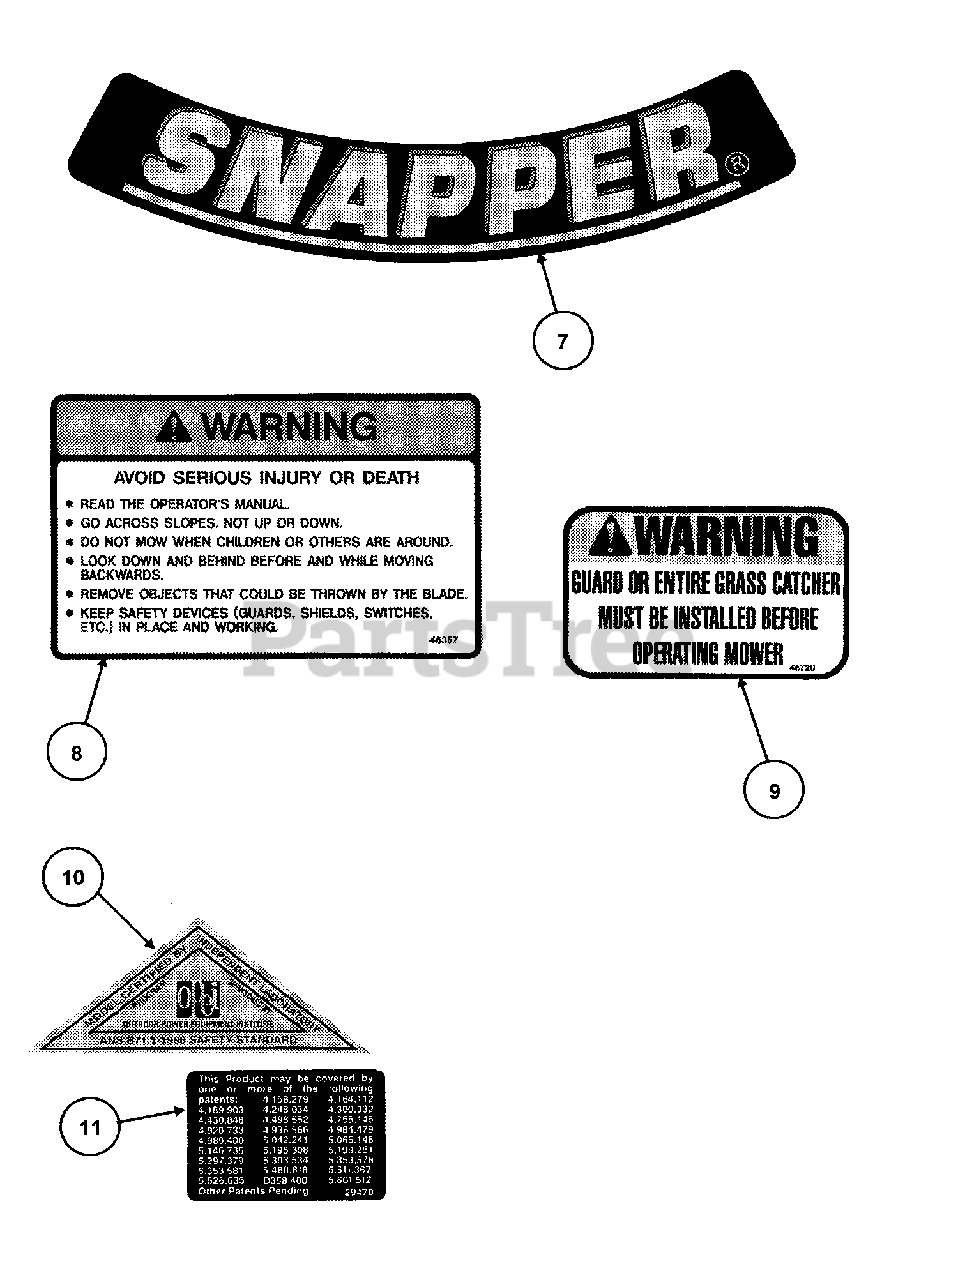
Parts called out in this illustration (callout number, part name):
7	DECAL, SNAPPER (Commercial)
8	DECAL, Warning
9	DECAL, Warning Chute/Deflector
10	DECAL, OPEI
11	DECAL, Patent Numbers
